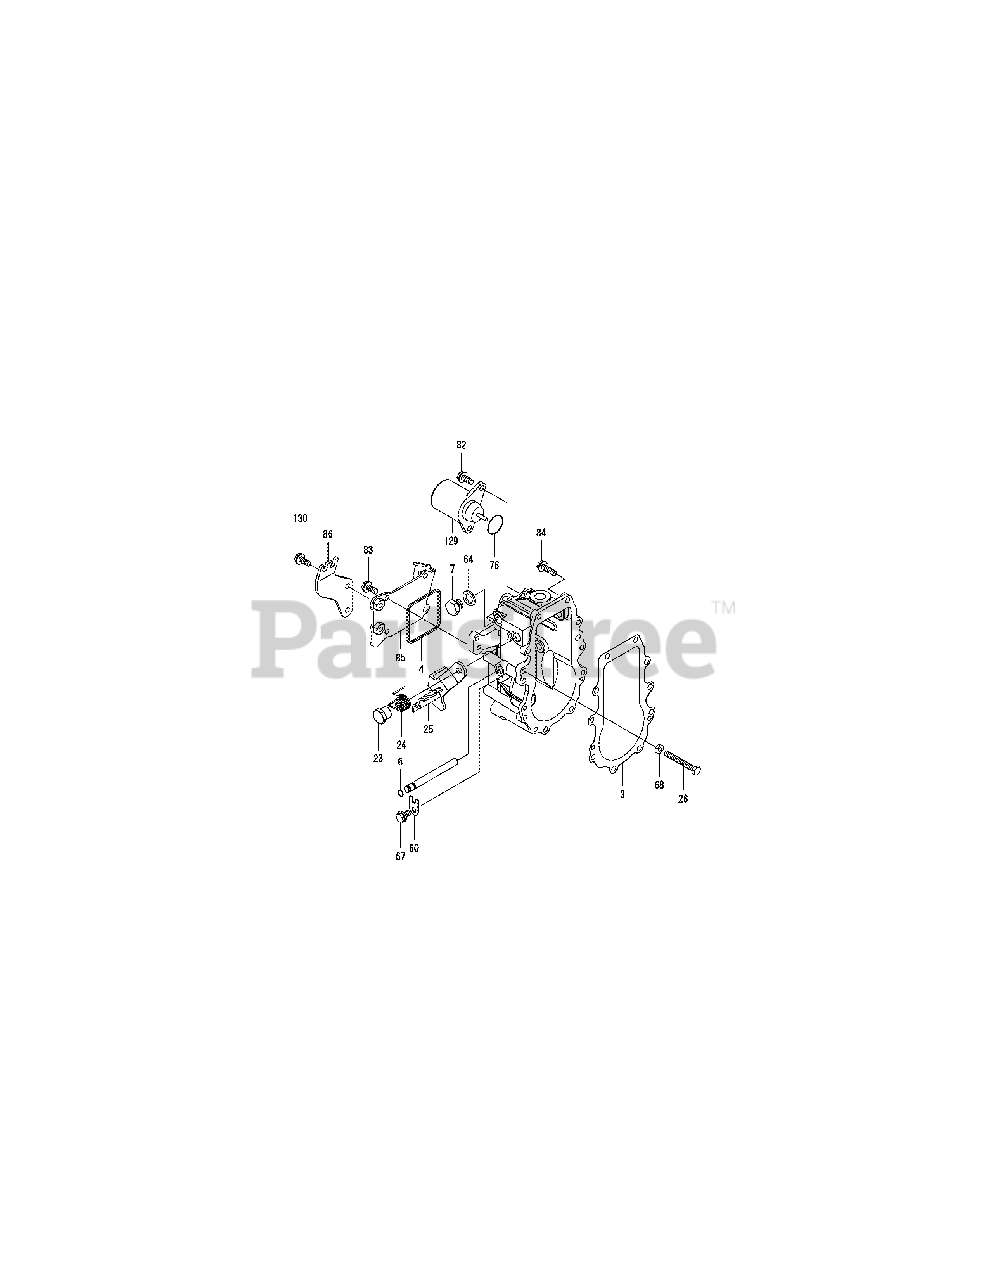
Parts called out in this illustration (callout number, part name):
4	PACKING, COVER
24	SPRING, RETURN
25	LEVER ASSY,REGULATOR
60	RETAINER, SHAFT
64	SEAL WASHER 12
67	BOLT 6X 10 PLATED
82	BOLT M 6X 14 PLATED
83	BOLT M 6X 14 PLATED
84	BOLT M 6X 20 PLATED
85	COVER, GOVERNOR CASE
129	SOLENOID, STOP
130	BOLT M 6X 14 PLATED
